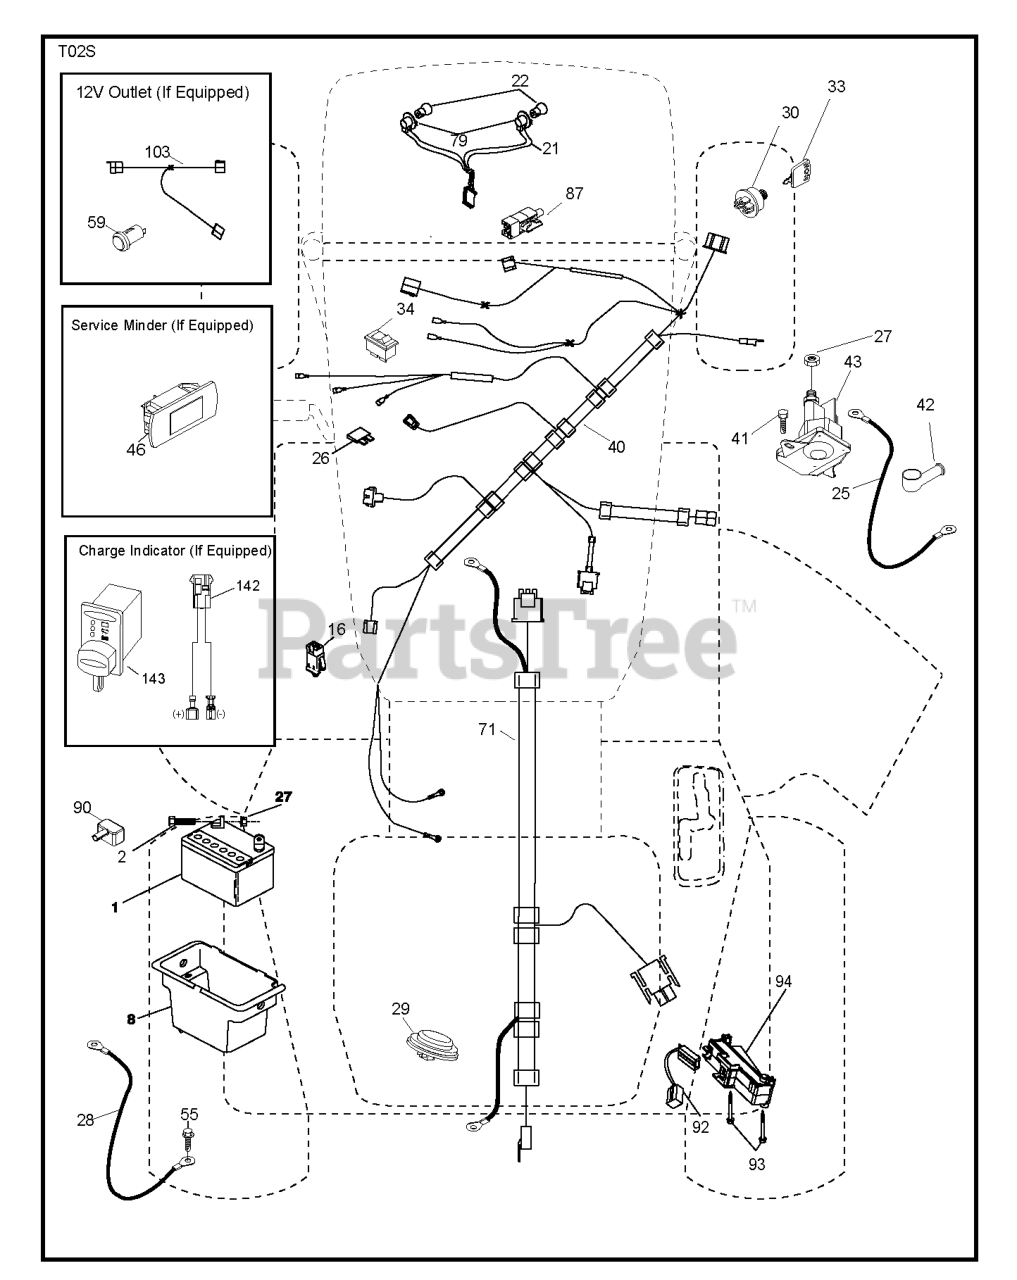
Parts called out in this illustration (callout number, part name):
1	REPL BY 532 12 38-99
2	BOLT.HEX.1/4.X.3/4.DICHROMATE
8	BOX.BATTERY.MNT.REAR.L
16	SWITCH INTERLOOK PUSH-IN
21	HARNESS.LIGHT W/4152J BULBS
25	CABLE.STARTER.8GA.14
26	FUSE 20AMP
27	NUT
28	CABLE.BLACK.18"REAR.BA
29	SWITCH.SEAT.DELTA.OPC.
30	SWITCH.IGN.DELTA.W.LGH.ROS
33	KEY.CHAIN.BLISTER.PACK.GEN.INT
40	HARNESS IGN. DASH
41	SCREW
42	TERMINAL COVER
43	SOLENOID.W/BRASS.PLUNGER
55	SCREW 5/16"
71	HARNESS.CHASSIS.TEX.8AWG
79	BULB HOLDER ASM.
87	SWITCH.INTRLCK.CLUTCH.
90	COVER.TERMINAL.BATTERY
92	HARNESS.PIGTAIL.CONSLE
93	SCREW.PLASTITE
94	MODULE.REVERSE.ROS
